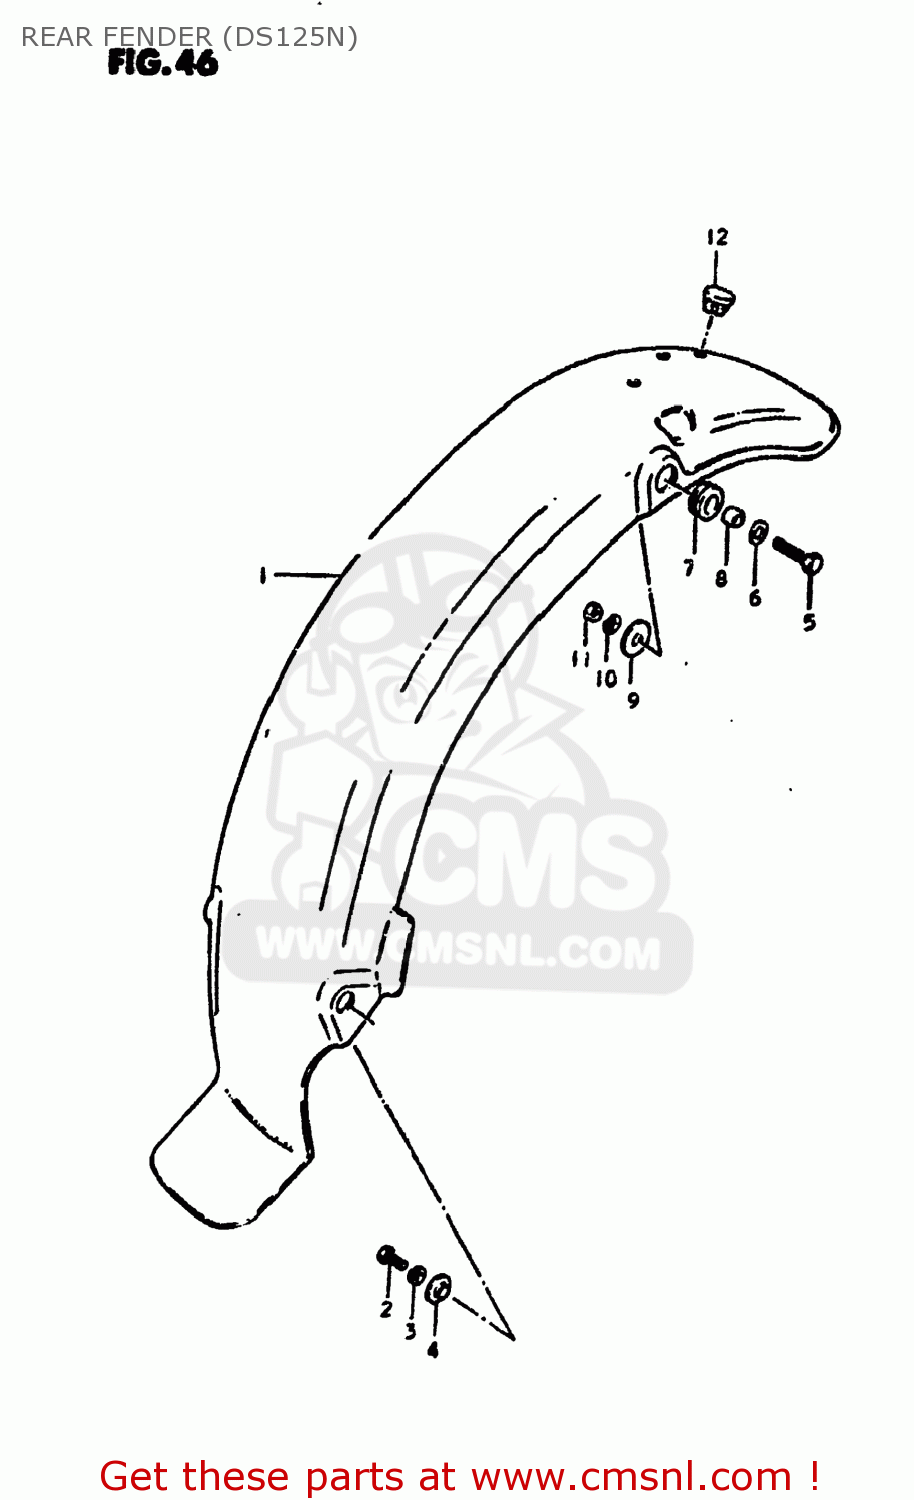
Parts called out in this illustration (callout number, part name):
1	FENDER,REAR
2	BOLT, UPPER
3	LOCK WASHER
4	WASHER
5	BOLT (8X30)
6	WASHER
7	CUSHION
8	SPACER (8.2X12X7.5)
9	WASHER(8.5X26X1.2)
10	LOCK WASHER
11	NUT
12	CUSHION
